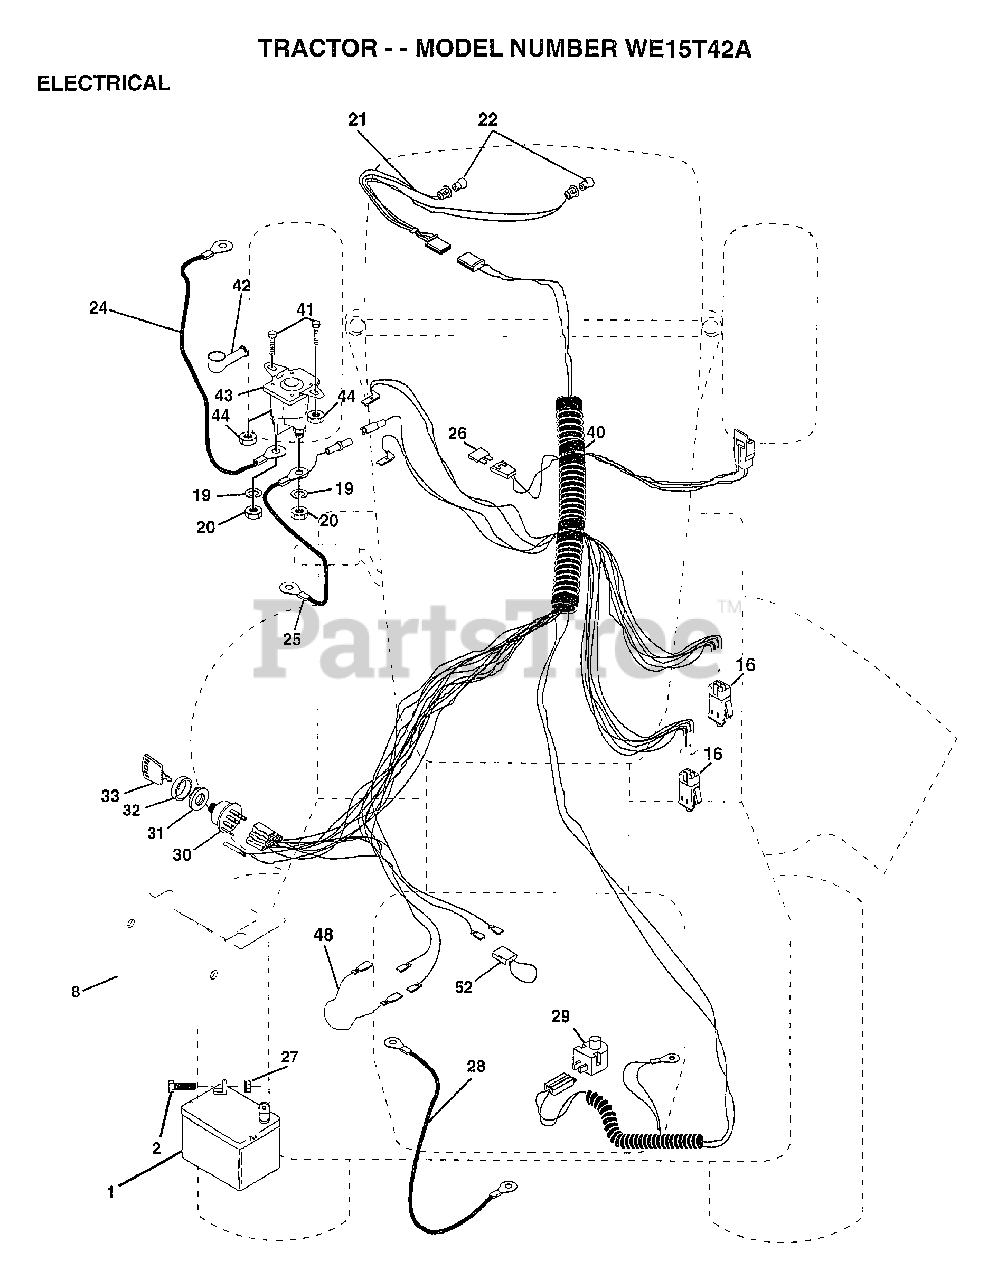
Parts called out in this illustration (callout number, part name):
2	BOLT LT
8	"CASE,BATTERY.MECH"
16	SWITCH INTERLOCK
20	NUT
21	HARNESS.ASM.LIGHT W/4152J
22	HEADLAMP BULB
24	CABLE ASM.
25	CABLE.BTRY.6GA.RD
26	FUSE.15 AMP
27	NUT
28	CABLE T
29	SWITCH SEAT
30	SWITCH IGN 4POS
31	NUT IGNITION
32	COVER KEY SWITCH
33	KEY
40	HARNESS.IGNITION
41	BOLT HXHD FIN
44	NUT HXKEP 1/4X20
48	ADAPTER AMMETER
52	PROTECTION LOOP
